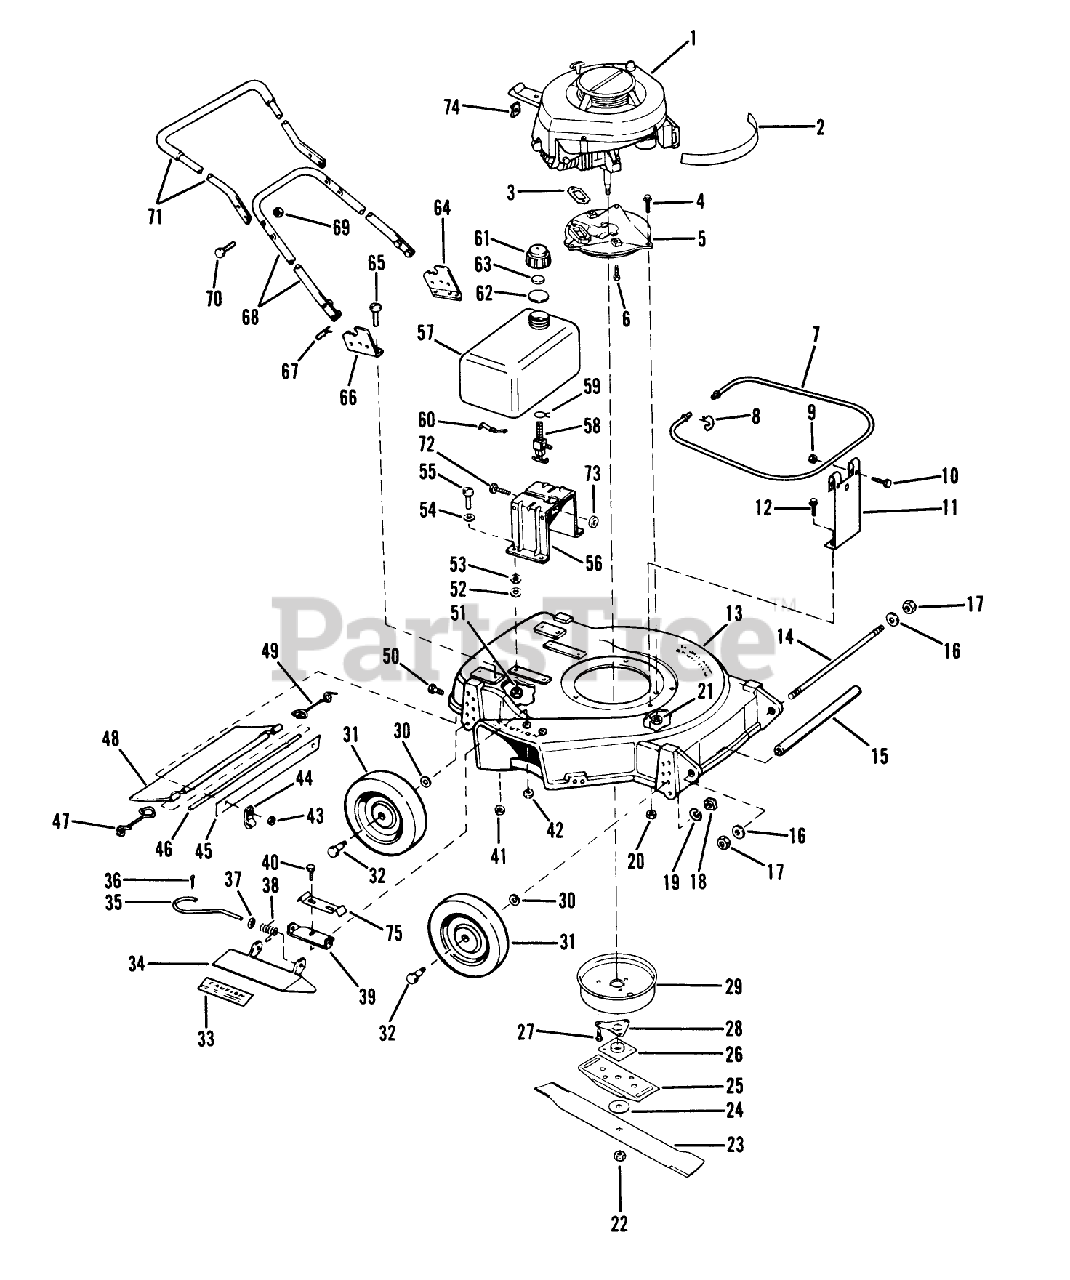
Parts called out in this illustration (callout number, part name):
6	SCREW V
9	LOCKNUT E
16	WASHER WROUGHT
17	LOCKNUT
18	NUT
19	WASHER, LOCK
20	LOCKNUT E
21	NUT-LOCK F
22	NUT-BLADE
24	WASHER
26	PLATE AND COLLAR ASM
27	SCREW
28	SUPPORT F
30	WASHER WROUGHT
35	HINGE PIN
40	SCREW HEX WASHER
41	LOCKNUT E
42	LOCKNUT E
43	LOCKNUT E
47	SPRING;TRAILING SHIELD RH
49	SPRIG T/SHLD ASOC
51	LOCKNUT E
52	WASHER
54	WASHER
55	BOLT PIONEER
58	VALVE&SCREEN SM
59	CLAMP - HOSE S
60	SPRING
62	GASKET S
63	BAFFLE - FOAM SM
65	SCREW S
69	LOCKNUT E
72	SCREW S
74	NUT-SPEED
